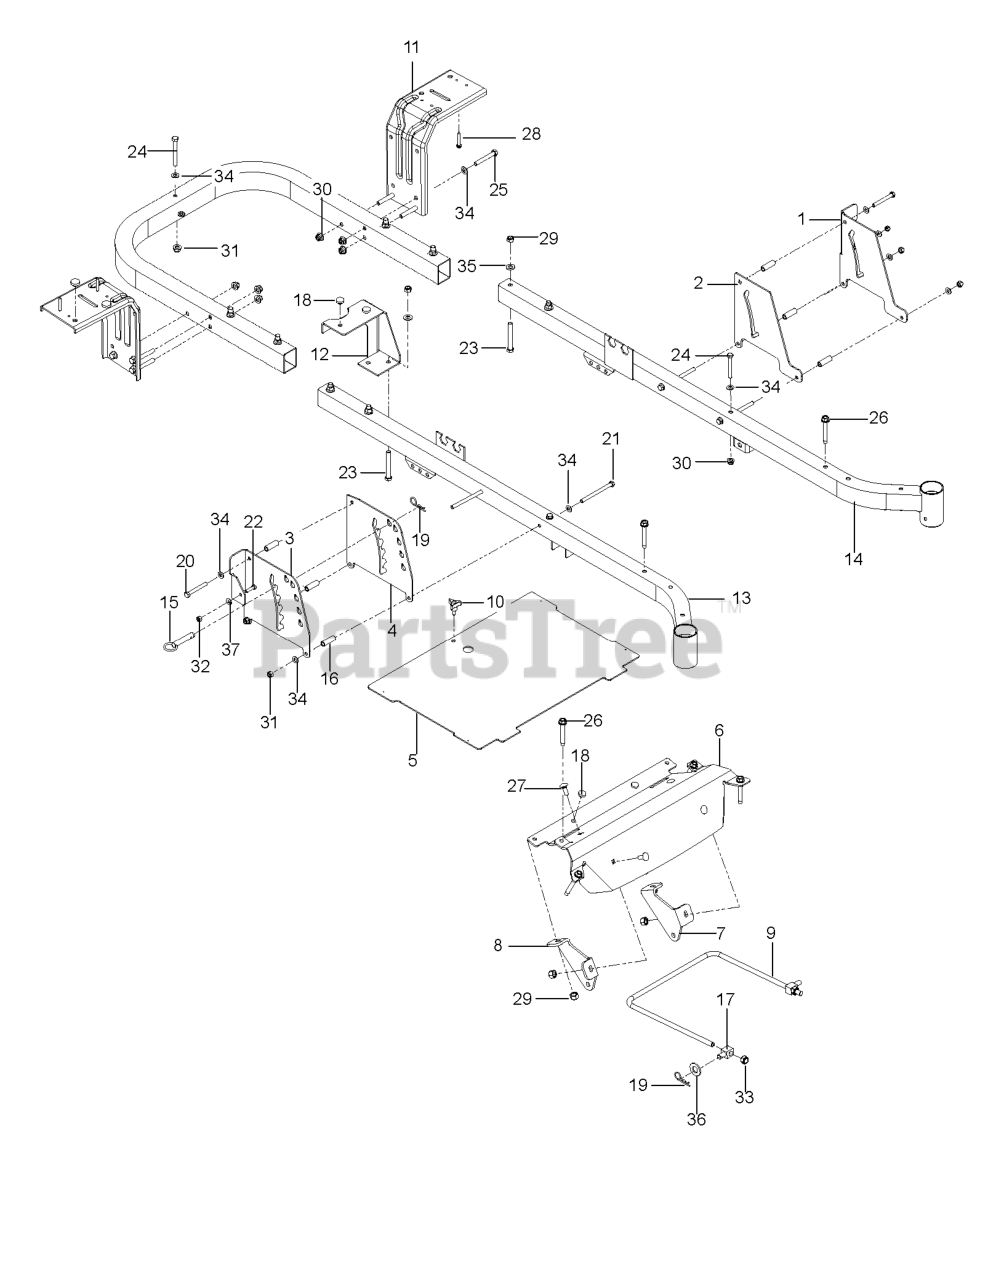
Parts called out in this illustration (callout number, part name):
1	PLATE, OUTER BRAKE, BLACK
2	PLATE, BRAKE LATCH, BLACK
3	PLATE, HEIGHT ADJ, BLACK
4	PLATE, DECK HEIGHT, BLACK
5	PLATE, FOOT W/DECALS RZ
6	FOOT.REST.MED.ORANGE
7	MOUNT.STRUT.LH.431
8	MOUNT.STRUT.RH.431
9	LINK, FRONT SUSP.
10	KNOB W/STUD
11	FENDER.SUPPORT.PNT.X431
12	SUPPORT, TANK, BLACK
13	FRAME, RT, ORANGE
14	FRAME, LT, ORANGE
15	PIN.DECK.HEIGHT.RZ
16	SPACER.334.ID.5.OD.1.5.L
17	SWIVEL.TRUNION.LINK.DECK.FRONT
18	GROMMET, BUMPER
19	HAIRPIN #4
20	HCS 5/16-18 X 2-1/2 GR 5 ZD
23	BOLT.HEX.FIN.3/8-16 X 3.GR5
26	HHFS 3/8-16 X 3 GRD 5 ZD
27	RHSNB 3/8C X 1
28	SCR #10-12X1-1/2HEX WASH HD ZD
29	NUT 3/8-16 NYLOC
30	5/16-18 NYLOC FLANGE NUT
31	NUT.71038.31-18.HEX.NYLOCK
32	NUT.1/4-20.HEX.NYLOC.ZD
33	7/16-14 HEX NUT W/NYL RING ZD
34	WASHER
35	WASHER 3/8 SAE FLAT
36	WASHER.9/16 X 1 3/8 X 12 GA.
37	WASHER 1/4 SAE
